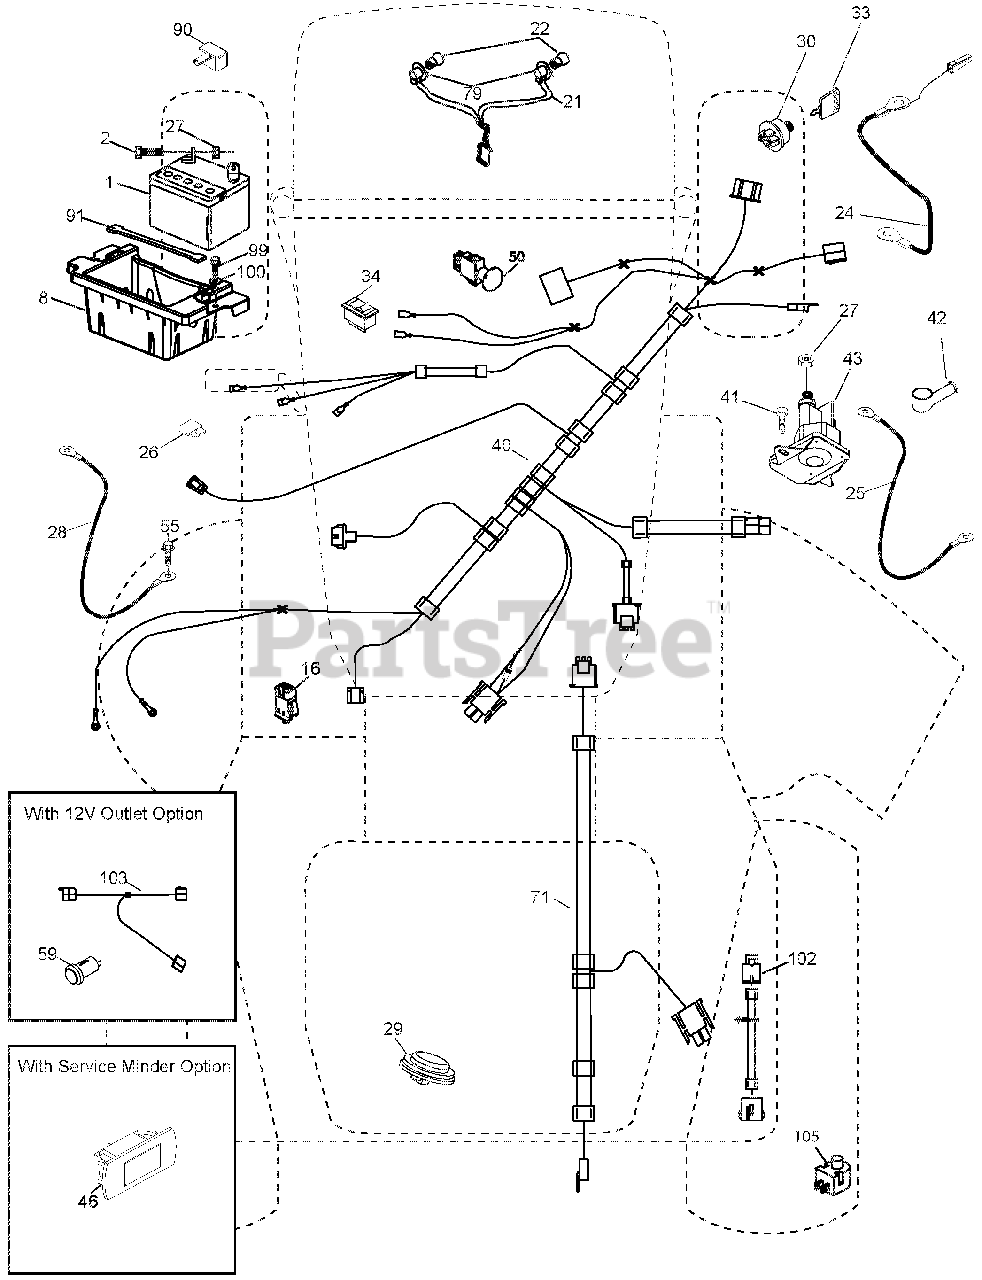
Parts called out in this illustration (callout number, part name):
1	BATTERY.12.VOLT.28.AMP.WET
2	BOLT.HEX.HD.1/4-20UNC X 3/4
8	BOX.BATTERY.MOUNT.FRONT.LT
16	SWITCH.INTERLOCK.NONO.GRAY
21	HARNESS ASM.LIGHT.22"(4152J)
22	BULB.LIGHT.#1156
24	CABLE.BTRY.PSWRE.DSH SOL.8"TEX
25	CABLE.STARTER.6GA.BL/RED.14.5"
26	FUSE.20 AMP.
27	Nut, Keps Hex 1/4-20 unc
28	CABLE.GROUND.21"BLK.6 GA.90T
29	SWITCH.SEAT.DELTA.OPC.9LB.
30	SWITCH.IGN.DLTA.P-IN.ROS
33	KEY/CHAIN.BLISTER PACK.GEN.CE
34	SWITCH.LIGHT/RESET.B/B/RED.
40	HARNESS.IGN.DASH.HUSQ/PRED.
41	Screw 1/4-20 x 1/2
42	COVER.TERMINAL.RED
43	SOLENOID.W/BRASS PLUNGER.2005
50	SWITCH.PTO.8 TERMINAL.BLACK
55	SCREW.5/16-18X3/4.SMGML.TAP/R
71	HARNESS.IGN.CHASSIS.TEX
79	SOCKET ASM.BULB.TWISTLOCK
90	COVER.TERMINAL.BATTERY.FR.TEX
91	STRAP.BATTERY.MOUNT.FRONT
99	SCREW.HEXWSH.THDROL.1/4-20X3/4
100	WASHER.9/32 X 7/8 X 16GA.
102	HARNESS.PIGTAIL.K46.TEX.ROS
105	SWITCH.REVERSE.TT.PEDAL CONTRO
